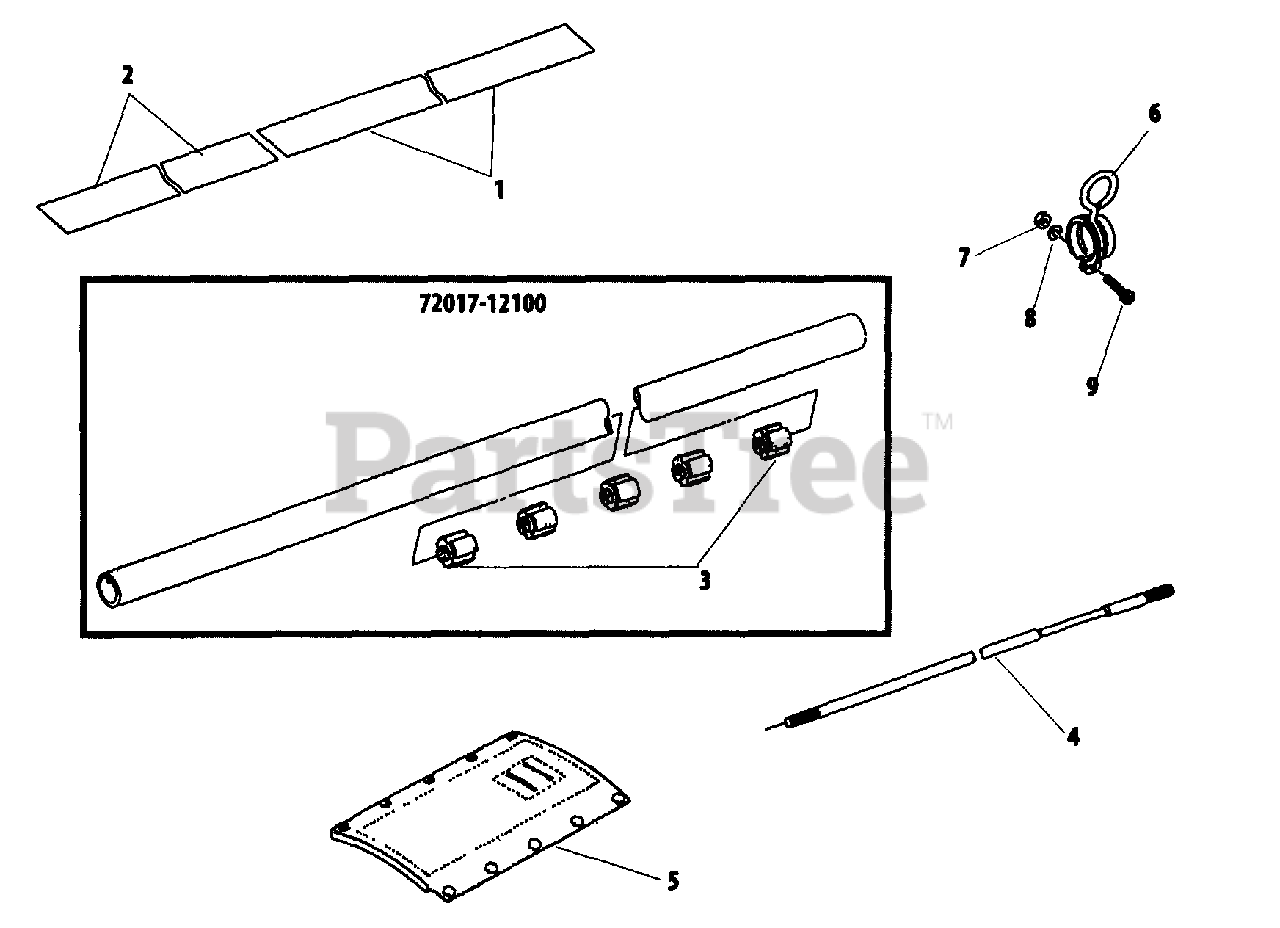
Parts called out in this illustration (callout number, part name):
1	LABEL - MODEL
2	LABEL - CAUTION
3	BUSHING
4	PIPE, MAIN
5	PROTECTOR
6	HANGER
8	LOCKWASHER - 5
9	SCREW - 5X12
72017-12100	MAIN PIPE ASSY
